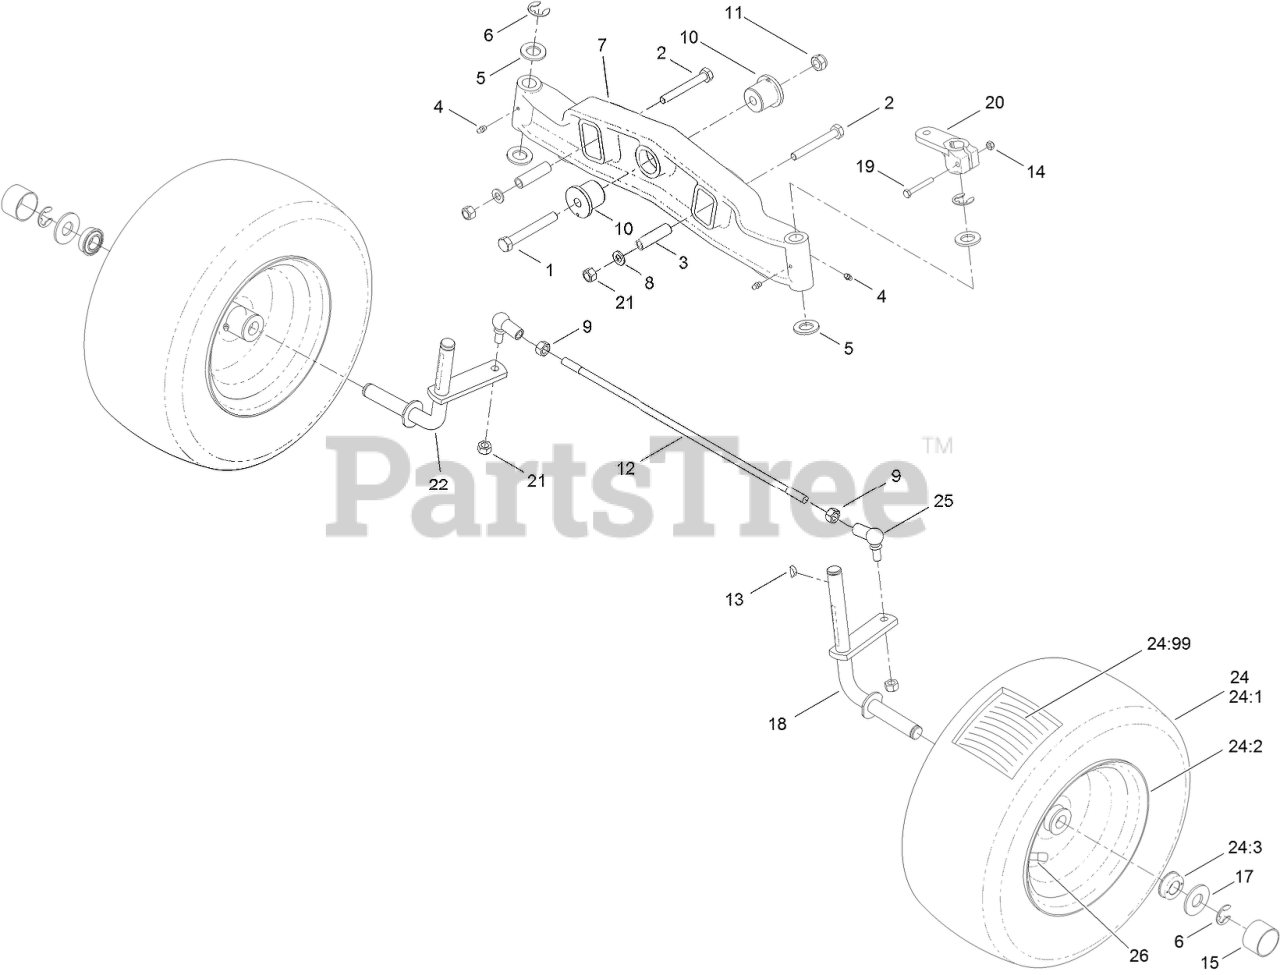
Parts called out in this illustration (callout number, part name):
1	SCREW-HH
2	SCREW-HH
3	SPACER
4	FITTING-GREASE
5	WASHER-FLAT
6	CLIP-SPRING
7	AXLE-FRONT
8	WASHER-FLAT
9	NUT
10	BUSHING-AXLE, FRONT
11	NUT-LOCKING, SELF
12	ROD-TIE, FRONT AXLE
13	KEY-WOODRUFF
14	NUT-LOCK
15	CAP-HUB
17	WASHER
18	SPINDLE-FRONT, LEFT
19	SCREW-HH
20	LEVER-SPINDLE, STEERING
21	NUT-LOCK, NI
22	SPINDLE-FRONT, RIGHT
24	WHEEL ASM
24:2	RIM-FRONT
24:3	BEARING-WHEEL
24:99	TUBE-INNER
25	JOINT-BALL, ANGLE
26	Valve-Tire
